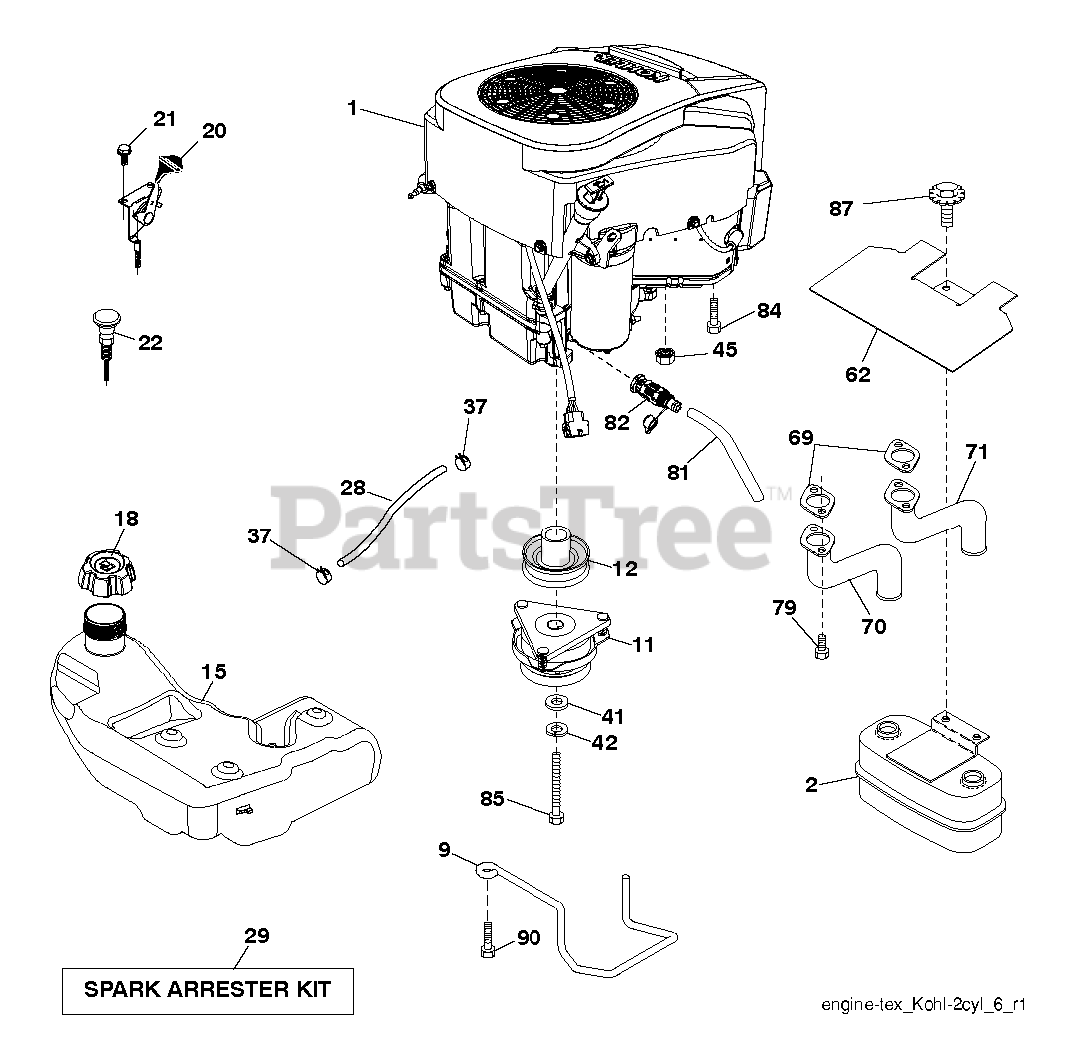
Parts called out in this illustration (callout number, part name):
2	MUFFLER.TWIN.CYL.LOW.TONE
9	KEEPER.BELT.ENGINE.4.2
11	RB.CLUTCH.OGURA.4.4.PD
12	PULLEY.ENGINE.TUFFTORQ
15	TANK.FUEL.4GAL
18	CAP.FUEL.TANK.3"GREY
20	THROTTLE CONTROL
21	SCREW
22	CONTROL.CHOKE.ERGO.PUSH-IN.BLA
28	REPL BY 532 00 85-43
29	KIT.SPARK ARRESTOR 794945 B&S
37	HOSE CLAMP
42	LOCKWASHER
45	NUT
62	RP SHIELD HEAT MUFFLER
69	EXHAUST SHROUDS
70	RP.PIPE-EXHAUST LH
71	RP.PIPE-EXHAUST RH
79	SCREW.SOCKET HD.5/16-1
81	TUBE, DRAIN OIL ASM.
82	PLUG DRAIN OIL EASY
84	SCREW 3/8-16X1
85	BOLT HEX 7/16-20X4-1/4"
87	BOLT.5/16-18UNCX1.W/SEMS.BLK
90	SCREW 3/8-16X1
